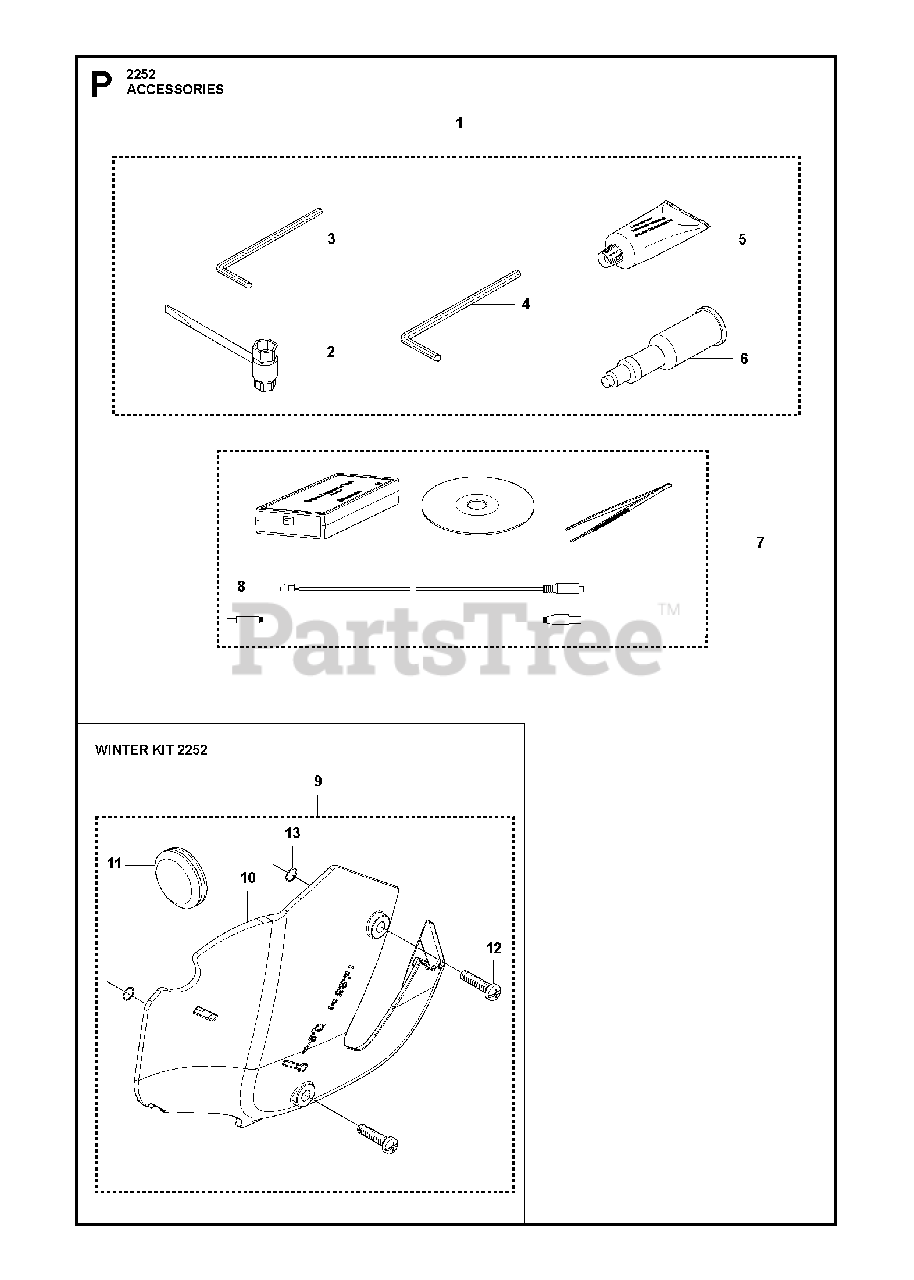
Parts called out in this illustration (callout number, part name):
2	COMBINATION WRENCH
3	L-SPANNER
4	L-SPANNER
5	GREASE
6	GREASE GUN
7	SERVICE TOOLS
8	CABLE ASSY
9	WINTER KIT
11	WINTER PLUG
12	SCREW
13	O-RING
